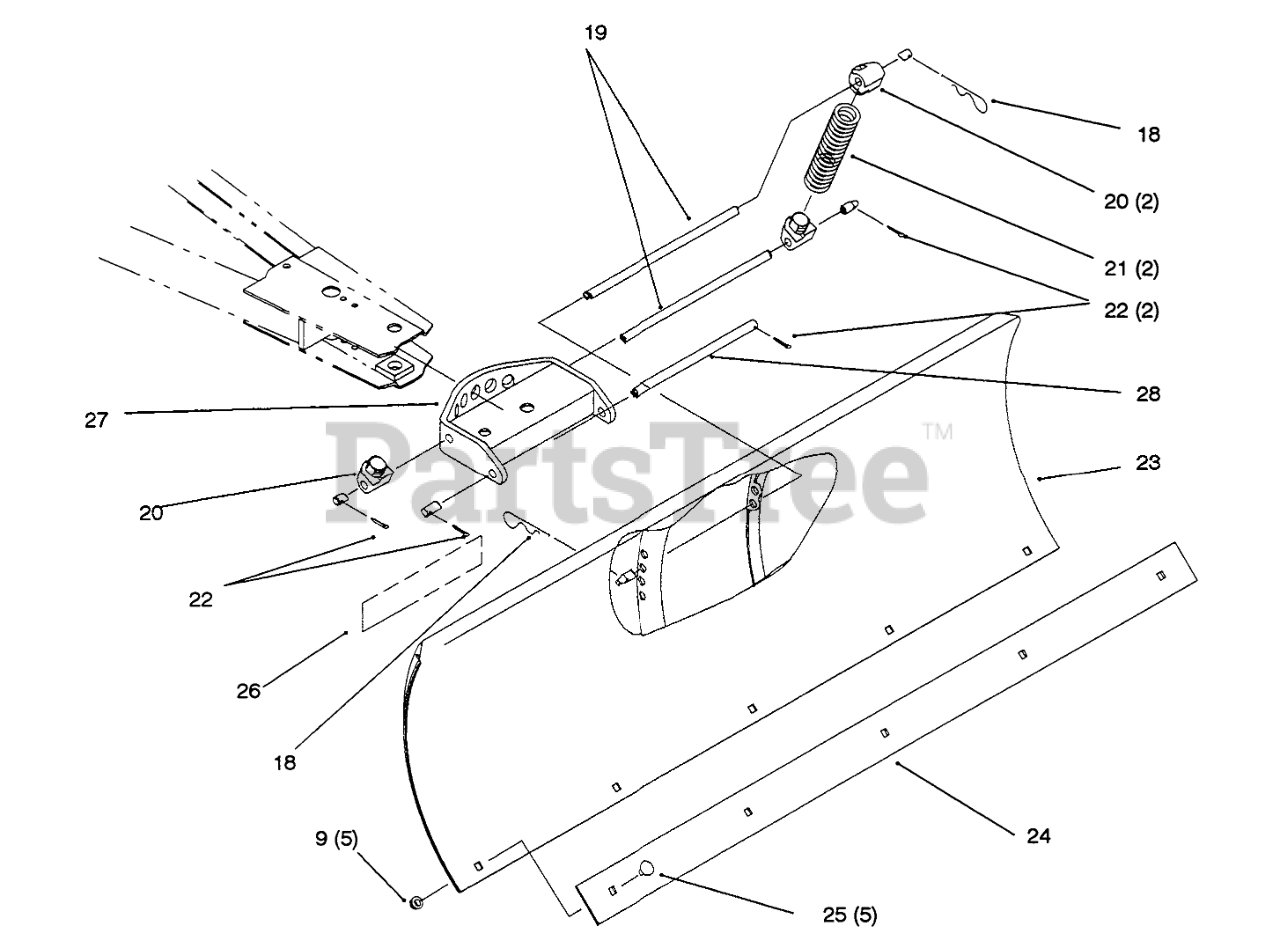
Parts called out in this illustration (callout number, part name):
9	NUT-LOCK, NI
18	PIN-HAIR
19	ROD-PIVOT, BLADE
20	Lug
21	Spring-Return
22	PIN-COTTER
23	BLADE ASM
24	Plate-Blade Edge
25	SCREW-CARR
26	DECAL-ATTACHMENT
27	Decal
28	ROD-LOWER
